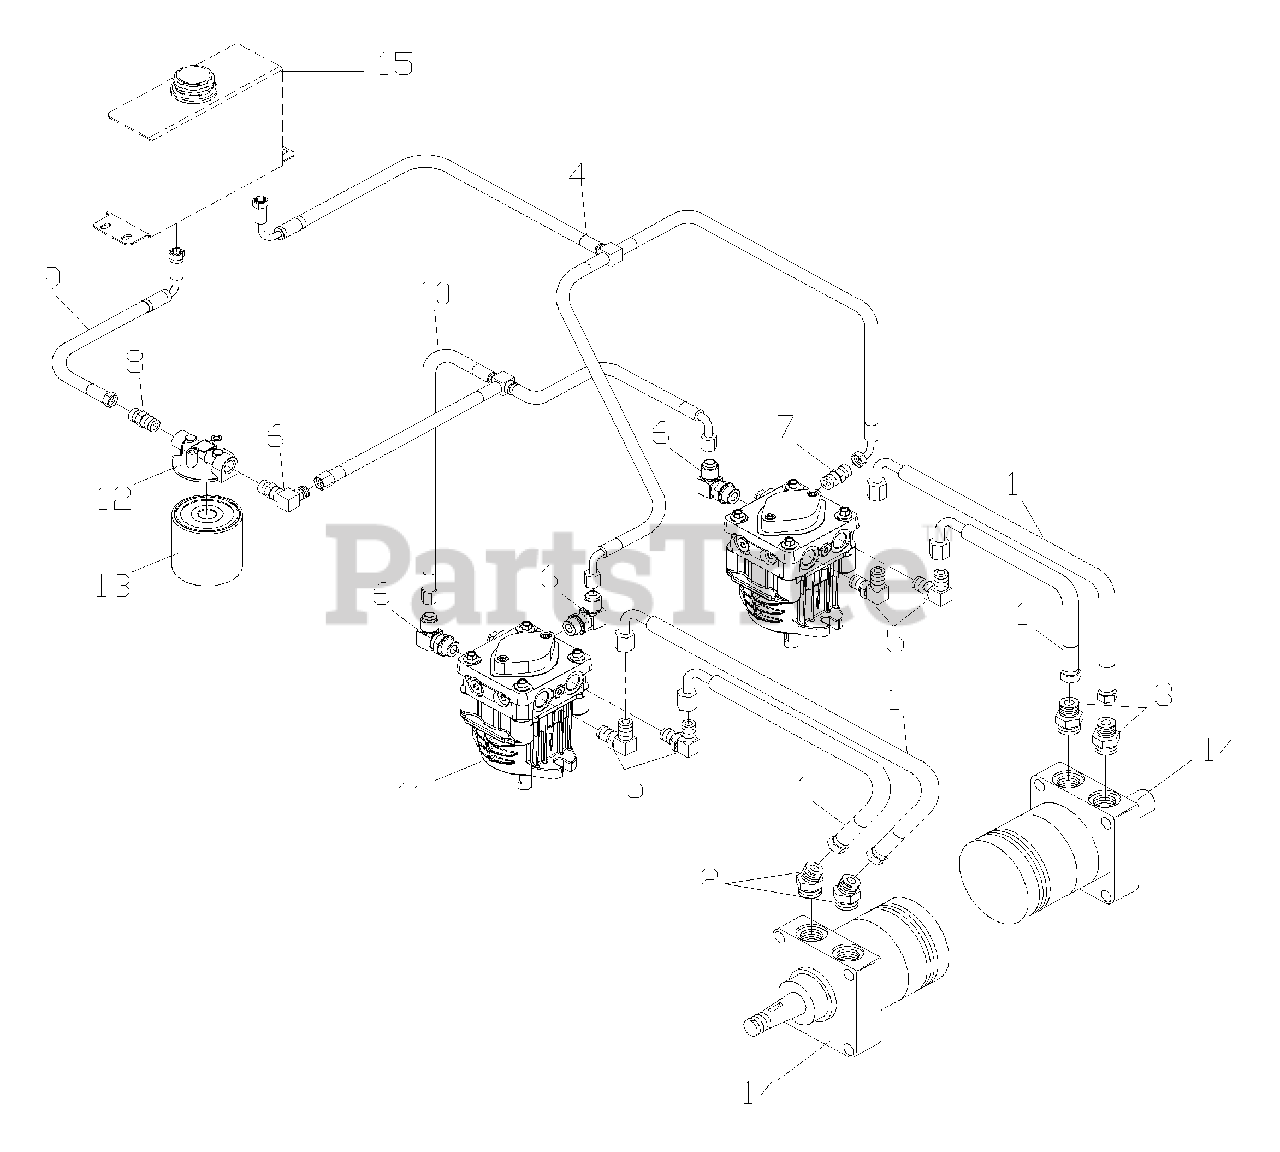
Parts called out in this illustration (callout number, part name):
1	1/2" HOSE
2	ELBOW 45 DEG.
3	CONNECTOR STRAIGHT
4	INLET TEE HOSE
5	ELBOW 90 DEG.
6	ELBOW 90 DEG.
7	CONNECTOR STRAIGHT
8	CONNECTOR STRAIGHT
9	HOSE
11	PUMP, 10A W/.031 POPPETS
12	FILTER HEAD
14	WHEEL MOTOR
15	HYDRAULIC TANK
